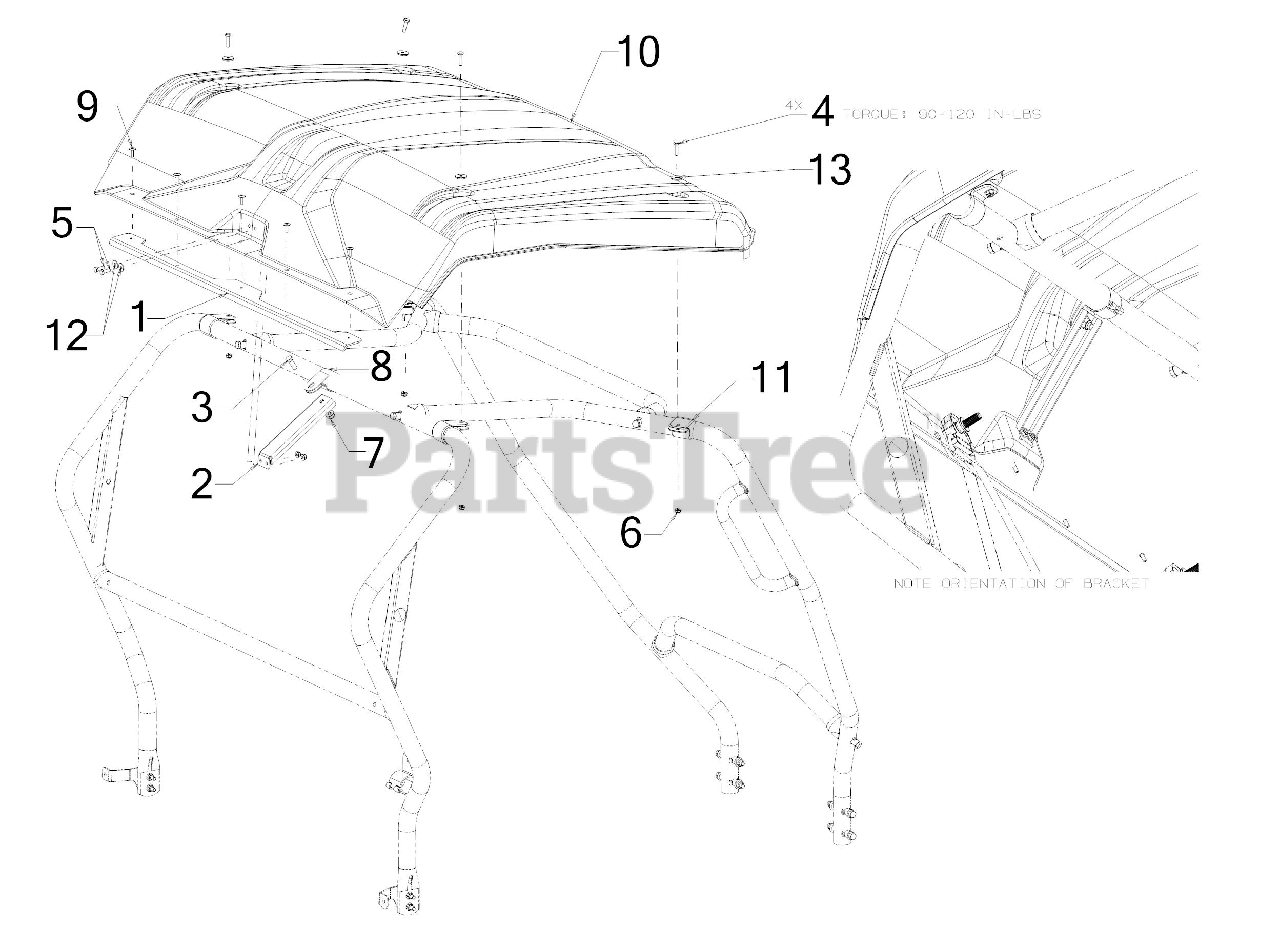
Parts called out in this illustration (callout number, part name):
1	CANOPY STIFFENER
2	CANOPY SUPPORT BRACKET
3	SCREW 3/8-16 x 1 GR5
4	SCREW 1/4-20 X1.00 GR5
5	SCREW 1/4-20X.75 GR5
6	FLANGE LOCK NUT
9	POP RIVET - .188 DIAMETER
10	ROOF
12	FLAT WASHER .28 ID x .74 OD x .063
13	FLAT WASHER .275 X 1.00 X .103
